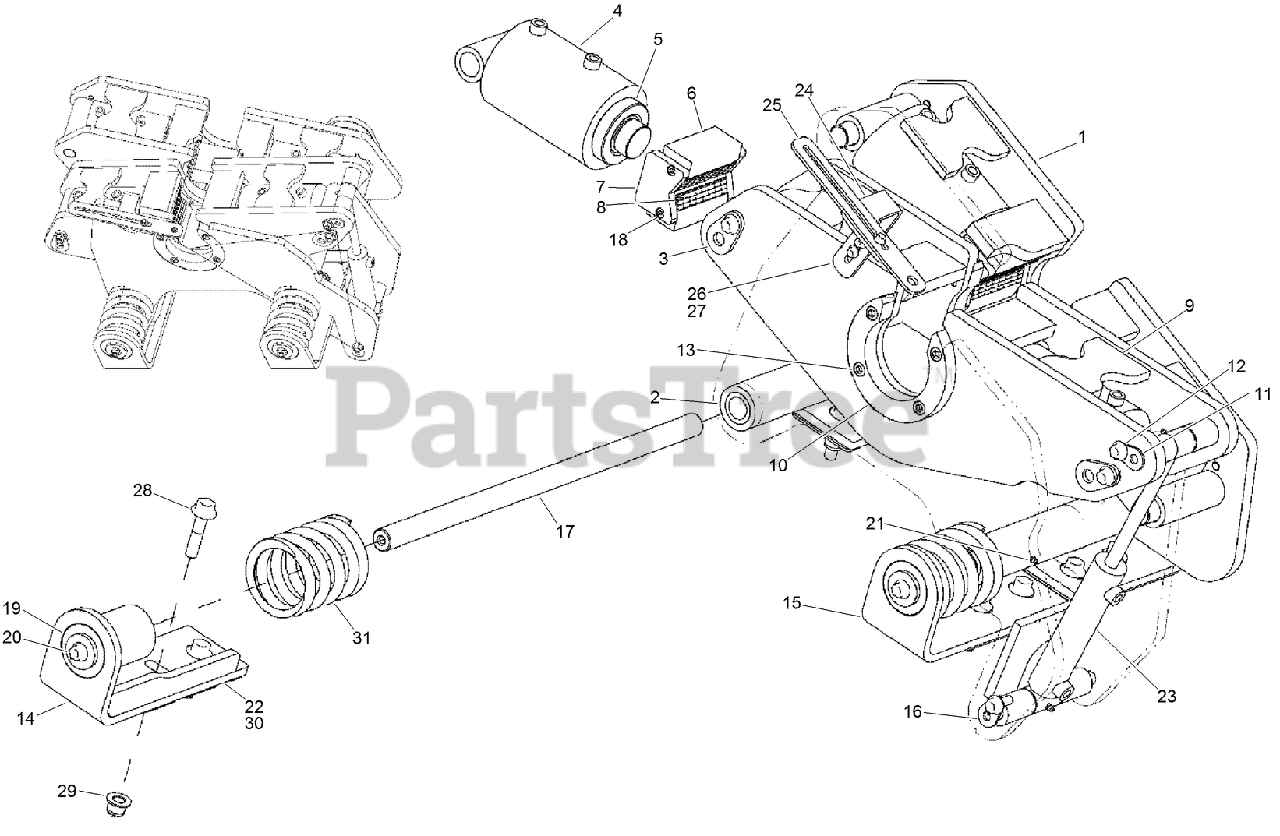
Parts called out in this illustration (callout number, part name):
1	WRENCH
2	BEARING - Flanged Sleeve
3	PIN-W/FLAG
4	HYD CYLINDER ASM
5	BUSHING - Cylinder
6	HOLDER-DIE, WRENCH
7	RETAINER - Wrench Die
8	TONG-DIE
9	WELDMENT - Wrench
10	GUIDE - Wrench
11	PIN-RETAINNG
12	SCREW, METRIC FLANGE w/BODY-M12 x 30
13	SCREW - Soc Hd M12 x 25 Class 12.9 BLO
14	BRACKET - Wrench Mounting
15	BRACKET - Wrench Mounting
16	PIN-RETAINING
17	PIN-WRENCH
18	SCREW - Soc Hd, M8 x 25 Class 12.9 BLO
19	WASHER - 0.531 x 2.000 x 0.25 in CST ZND
20	SCREW, METRIC FLANGE FULL - M12 x 50
21	FITTING-Lube 1/4-28 Tpr SAE-LT .54 Long
22	PLATE - Wrench Shim
23	HYD CYLINDER ASM
24	PLATE - Nozzle Mount
25	PLATE - Nozzle Mount
26	SCREW-HH
27	NUT-TORQUE, PREVAILING
28	SCREW-FLANGE
29	NUT-HHF
30	PLATE, Wrench Shim
31	SPRING-COMPRESSION
